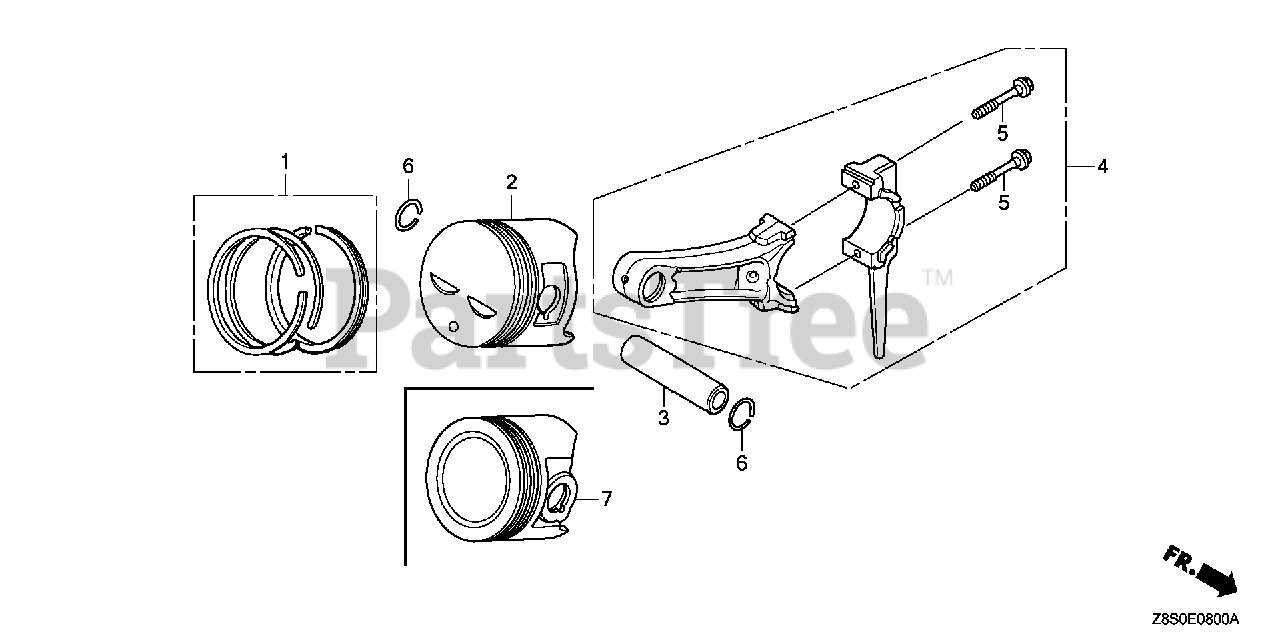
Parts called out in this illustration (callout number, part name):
1	RING SET, PISTON (STD) (TEIKOKU)
1	RING SET, PISTON (0.25) (TEIKOKU)
1	RING SET, PISTON (0.50) (TEIKOKU)
1	RING SET, PISTON (0.75) (TEIKOKU)
3	PIN, PISTON
4	ROD ASSY., CONNECTING (STD)
4	ROD ASSY., CONNECTING (0.25 LOWER SIZE)
5	BOLT, CONNECTING ROD
6	CLIP, PISTON PIN (18MM)
7	PISTON (STD)
7	PISTON (0.25)
7	PISTON (0.50)
7	PISTON (0.75)
